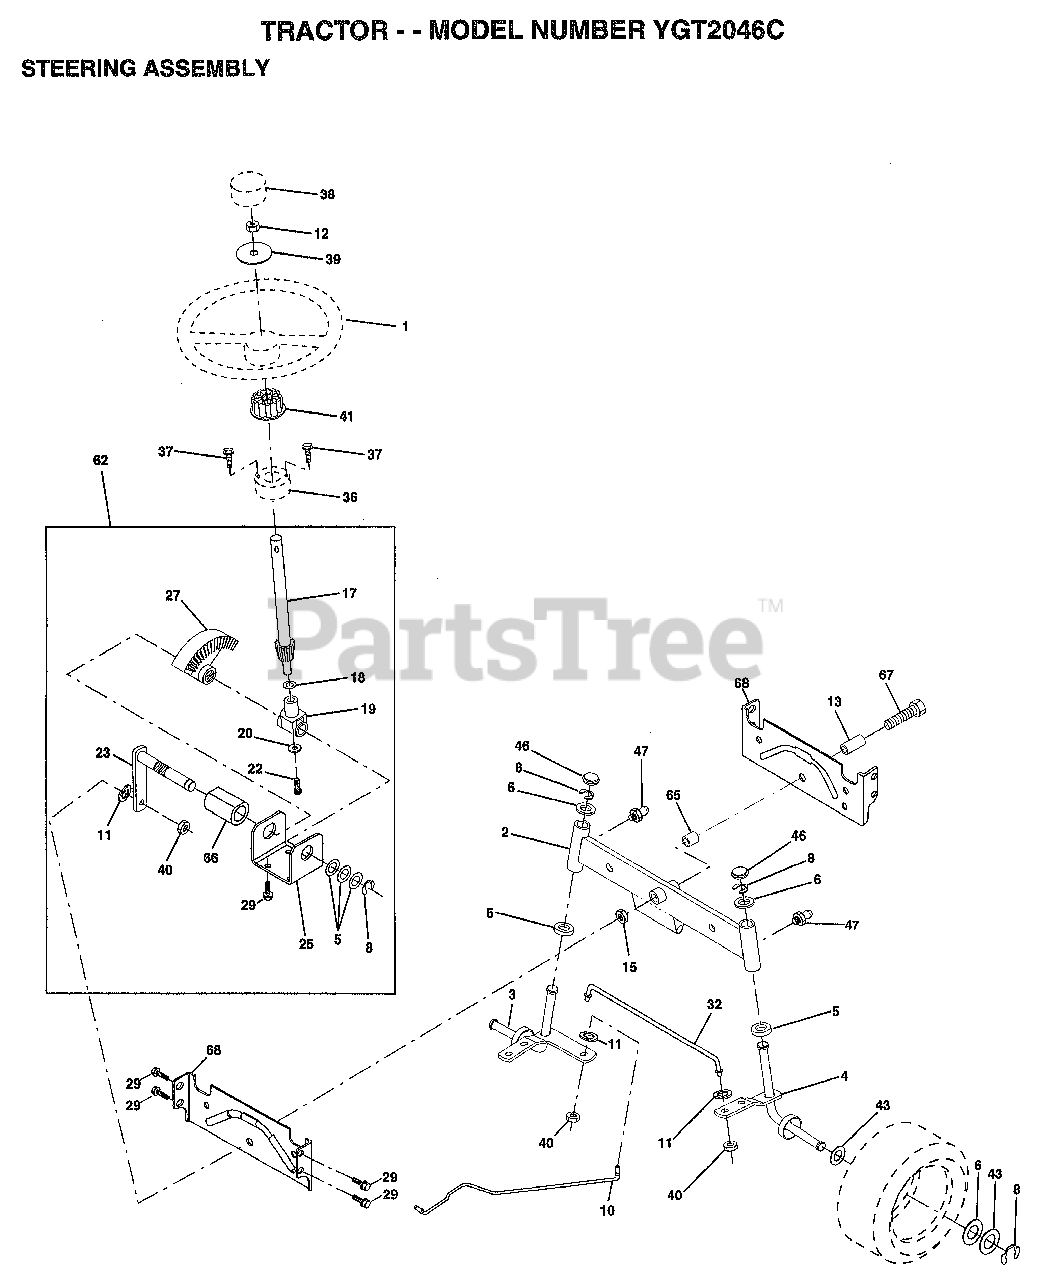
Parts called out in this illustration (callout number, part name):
3	"SPINDLE ASM,RH"
4	"SPINDLE ASM,RH"
5	WASHER .T
6	WASHER
8	RING
10	LINK.DRAG
11	LOCKWASHER
13	BEARING AXLE
15	"NUT-LOC,FLANGE LT"
17	STEERING SHAFT
18	THRUST WASHER
19	SUPPORT.SHAFT
22	SCREW HEX SOC1/4-
25	BRKT-STEERING
27	GEAR SECTOR
29	SCREW
32	ROD.ASM.TIE.BALL
36	BUSHING.STRG.3/4
37	"SCREW-TT,10-32 FL"
38	"INSERT,STR WHEEL"
39	WASHER
40	GRIPCO NUT
41	ADAPTER LT
46	CAP
47	ZERK M
62	STEERING KIT
65	SPACER AXLE
66	"BEARING-ARM,PITMA"
67	BOLT
68	BRACE AXLE
